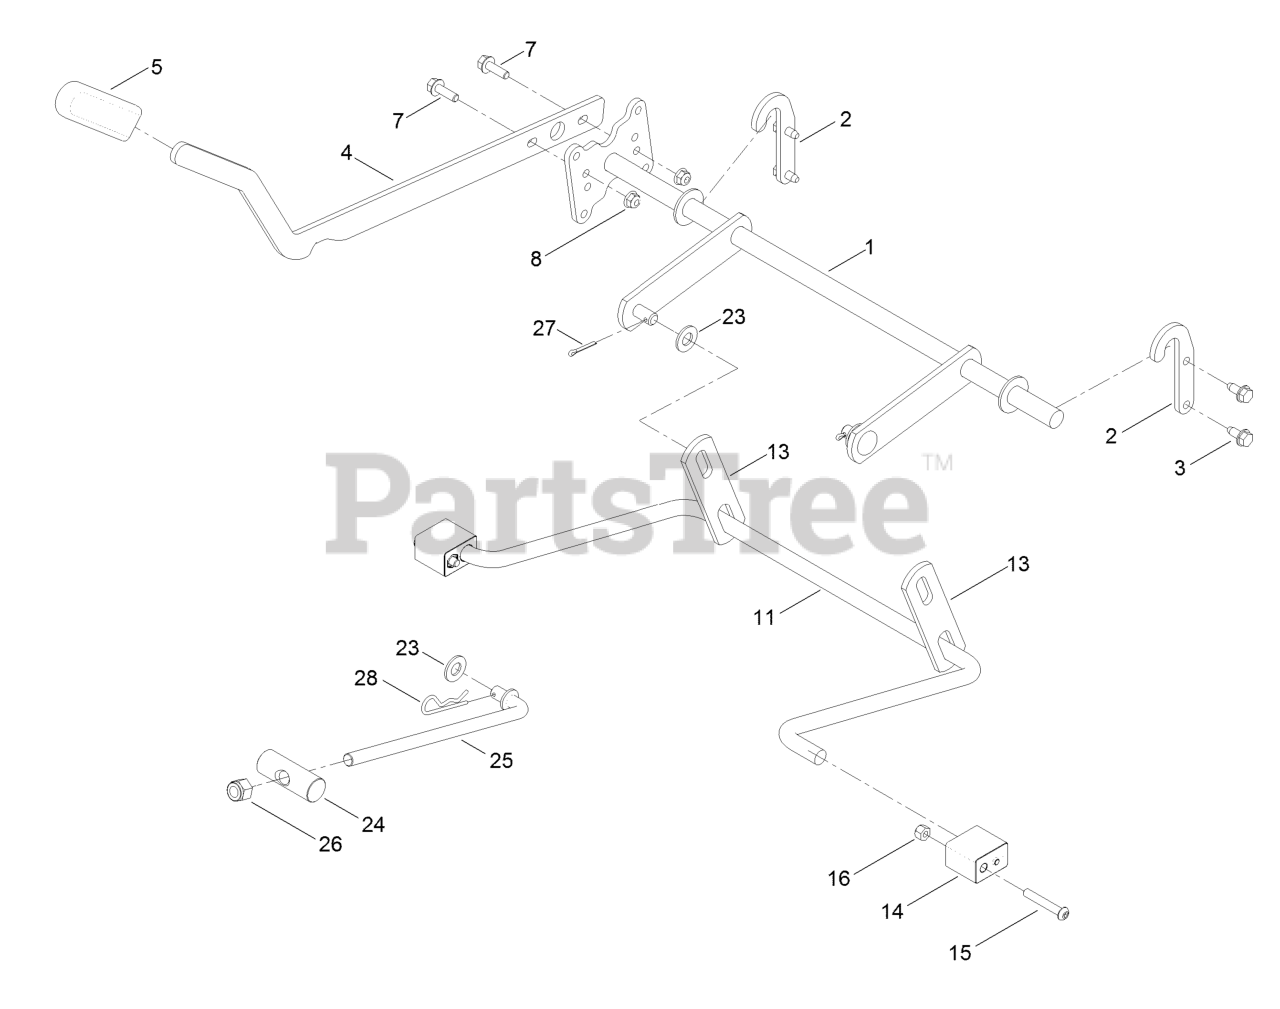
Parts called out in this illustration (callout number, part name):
1	LIFT-DECK, NARROW
2	BRACKET-LIFT
3	Screw-HWH 5/16-18 X 3/4 Tf
4	LEVER-LIFT
5	GRIP-LEVER
7	SCREW-HHF
8	NUT-HF, NI
11	ARM-LIFT, REAR
13	LINK-LIFT
14	BLOCK-PIVOT
15	SCREW-HSBH
16	NUT-LOCK, NI
23	WASHER-FLAT
24	PIN-PIVOT
25	ROD-MOUNT, DECK
26	NUT-HEX
27	PIN-COTTER
28	PIN-COTTER
